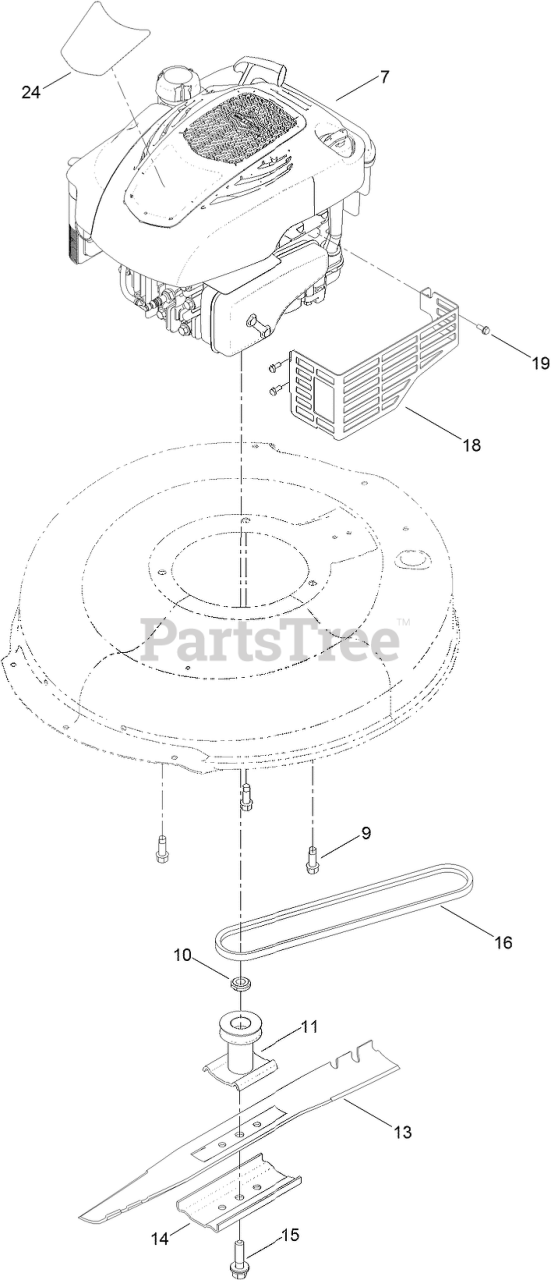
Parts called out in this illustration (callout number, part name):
9	SCREW-TAPTITE
10	Spacer-Driver
11	DRIVER-BLADE
13	BLADE-21 INCH
14	SUPPORT-BLADE
15	BOLT-BLADE
16	V-BELT
18	SHIELD-MUFFLER
19	SCREW-TAPTITE
24	DECAL-SHROUD
